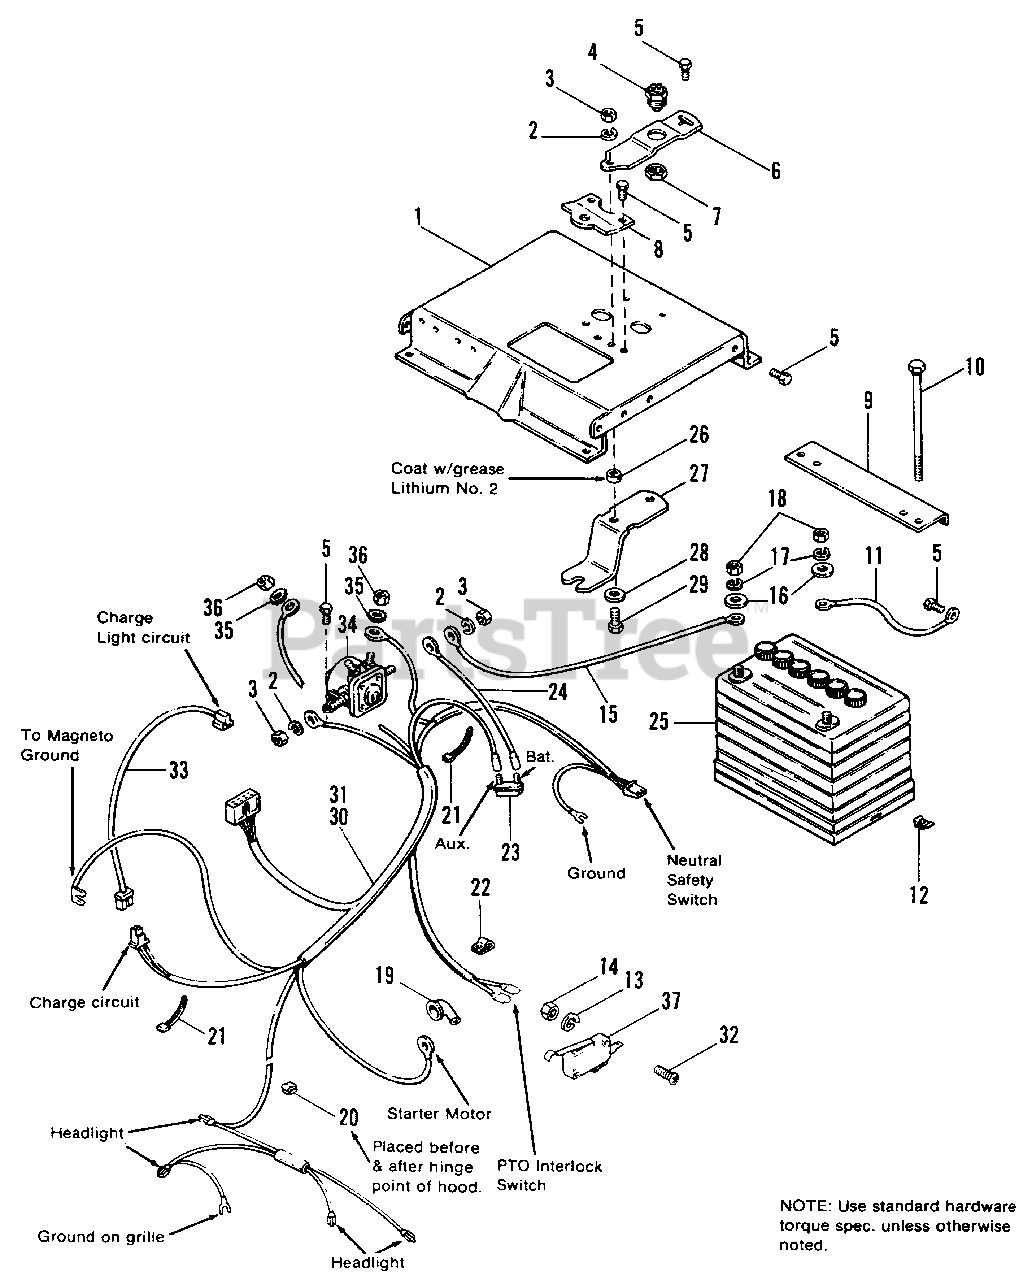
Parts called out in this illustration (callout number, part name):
1	SUPPORT FRAME
2	LOCKWASHER, 5/16
3	NUT, Hex, Full, 5/16-18
4	SWITCH, Interlock
5	SCREW, Hex, Taptite, 1/4-20 x 3/8
6	BRACKET, Switch
7	LOCKNUT, Hex, 9/16-18
8	PIVOT, Shift Lever
9	HOLD DOWN, Battery
10	CAPSCREW, Hex, 1/4-20 x 7-1/2
12	NUT, Retaining, 1/4-20
13	LOCKWASHER, #5
14	NUT, Hex, #5-40
16	WASHER, Plain, 1/4
17	LOCKWASHER, 1/4
18	NUT, Hex, Full, 1/4-20
19	COVER, Terminal
20	CLIP, Wire
21	TIE, Self-Locking
22	CLIP, Speed
23	BREAKER, Circuit
25	BATTERY, 39 Amp.
27	LEVER, Switch
29	CAPSCREW, Hex, 5/16-18 x 1
30	HARNESS, Lower (Includes Ref. No. 31)
31	DIODE ASSY.
32	SCREW, Rd. Hd. Phil., #5-40 x 3/4
33	WIRE ASSY. (Used on 6216 & 6218 Only)
34	SOLENOID
35	LOCKWASHER, Ext. #10
36	NUT, Hex, #10-32
37	SWITCH, P.T.O. Interlock
